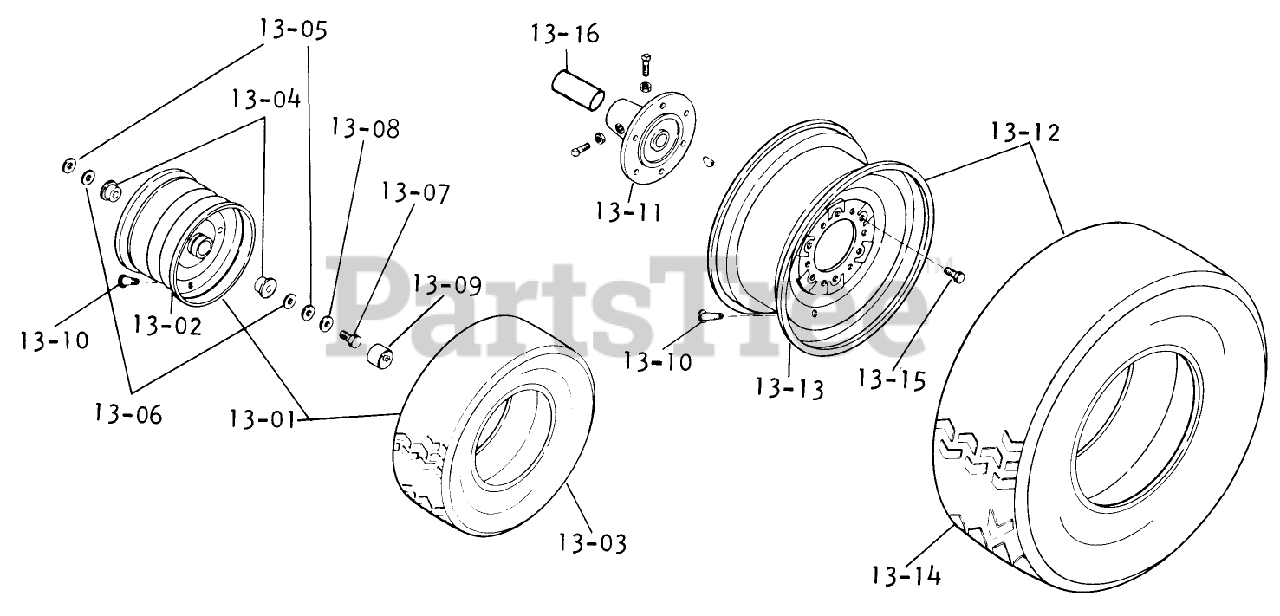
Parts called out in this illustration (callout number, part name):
13-02	BULLT 322
13-05	WASHER
13-06	WASHER-SHIM
13-07	Bolt 3/8-16 x 7/8
13-08	WASHER
13-15	BOLT-LUG, WHEEL
